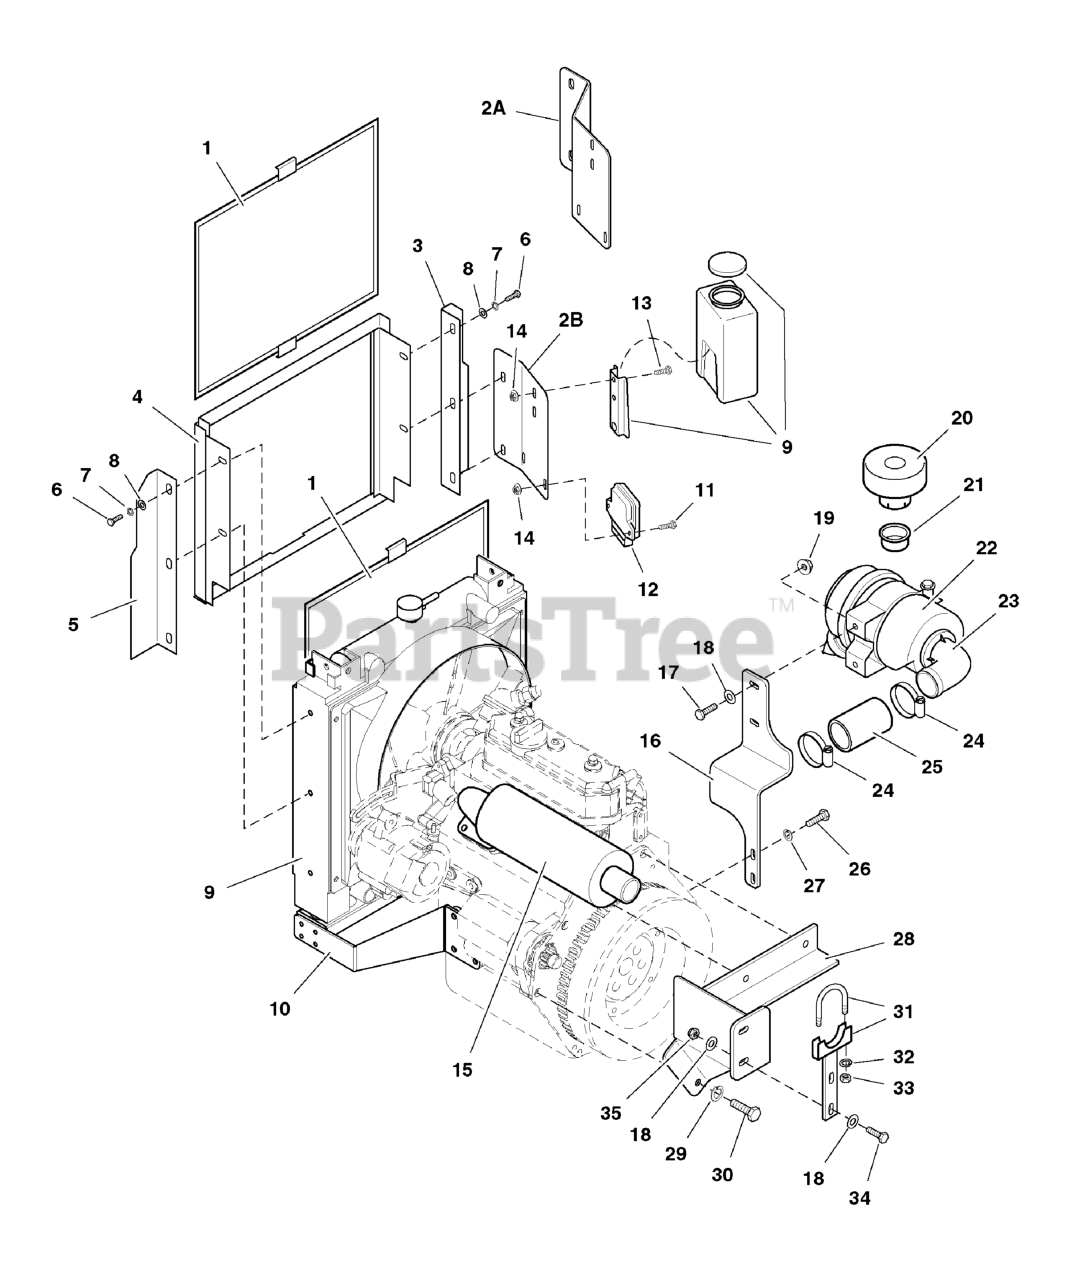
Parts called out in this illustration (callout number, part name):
1	RADIATOR SCREEN
2A	MOUNT, Overflow Bracket
2B	MOUNT, Overflow Bracket
3	AIR BAFFLE-RH
4	RADIATOR COVER
5	AIR BAFFLE-LH
7	WASHER, 1/4 LOCK
8	WASHER, 1/4 SAE
11	BOLT, 1/4-20 X 1" GD5 CZ
12	IGNITION MODULE
13	BOLT, 1/4-20 x 3/4
14	NUT, 1/4-20 HEX SERR. FLANGE
16	SUPPORT, Air Cleaner
17	BOLT, 5/16-18 X 3/4 GD5
18	WASHER, 5/16" SAE
19	NUT, 5/16-18 HEX SERRATED FLANGE (SMALL)
20	PRE-CLEANER
21	ADAPTER INSERT
24	HOSE CLAMP
26	BOLT, M8 x 35MM
27	WASHER, 5/16 LOCK CZ
28	SUPPORT, Muffler
29	WASHER, 10MM Lock
30	BOLT, M10 x 30MM
31	MUFFLER CLAMP, Complete
32	WASHER, 1/4 LOCK
33	NUT, 1/4-20 Hex
34	BOLT, 5/16-18 X 1 GD5 YZ
35	NUT, 5/16-24 HEX NYLON LOCK
